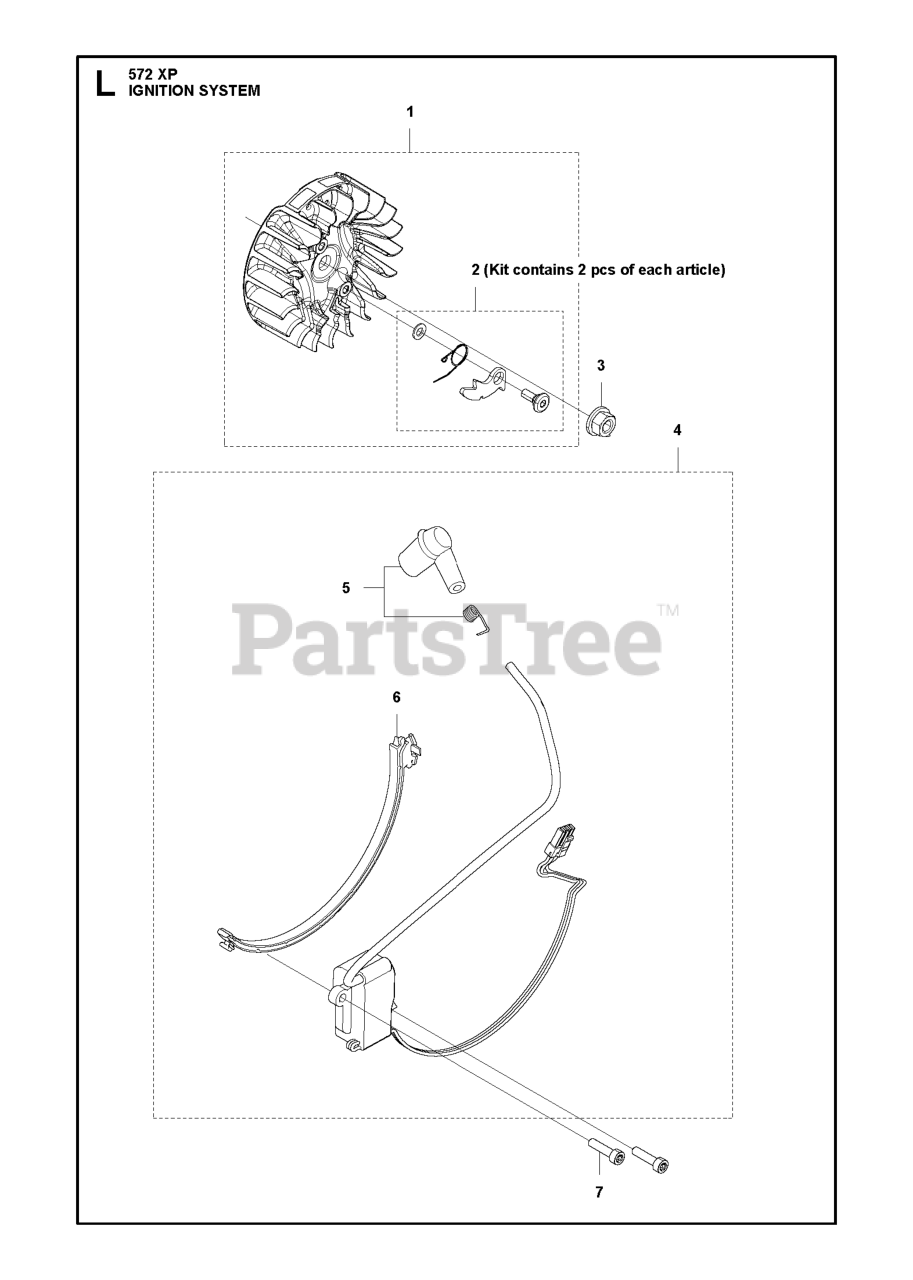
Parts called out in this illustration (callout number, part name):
1	FLYWHEEL ASSY SPARE PART H565/
1	FLYWHEEL ASSY SPARE PART H572X
2	PAWL KIT - SPARE PART H565/H57
3	NUT W/ WASHER
4	IGNITION MODULE ASSY H572XP MB
5	SPARK PLUG CAP ASSY - SPARE PA
6	WIRE HOLDER
7	SCREW ITXSCM
